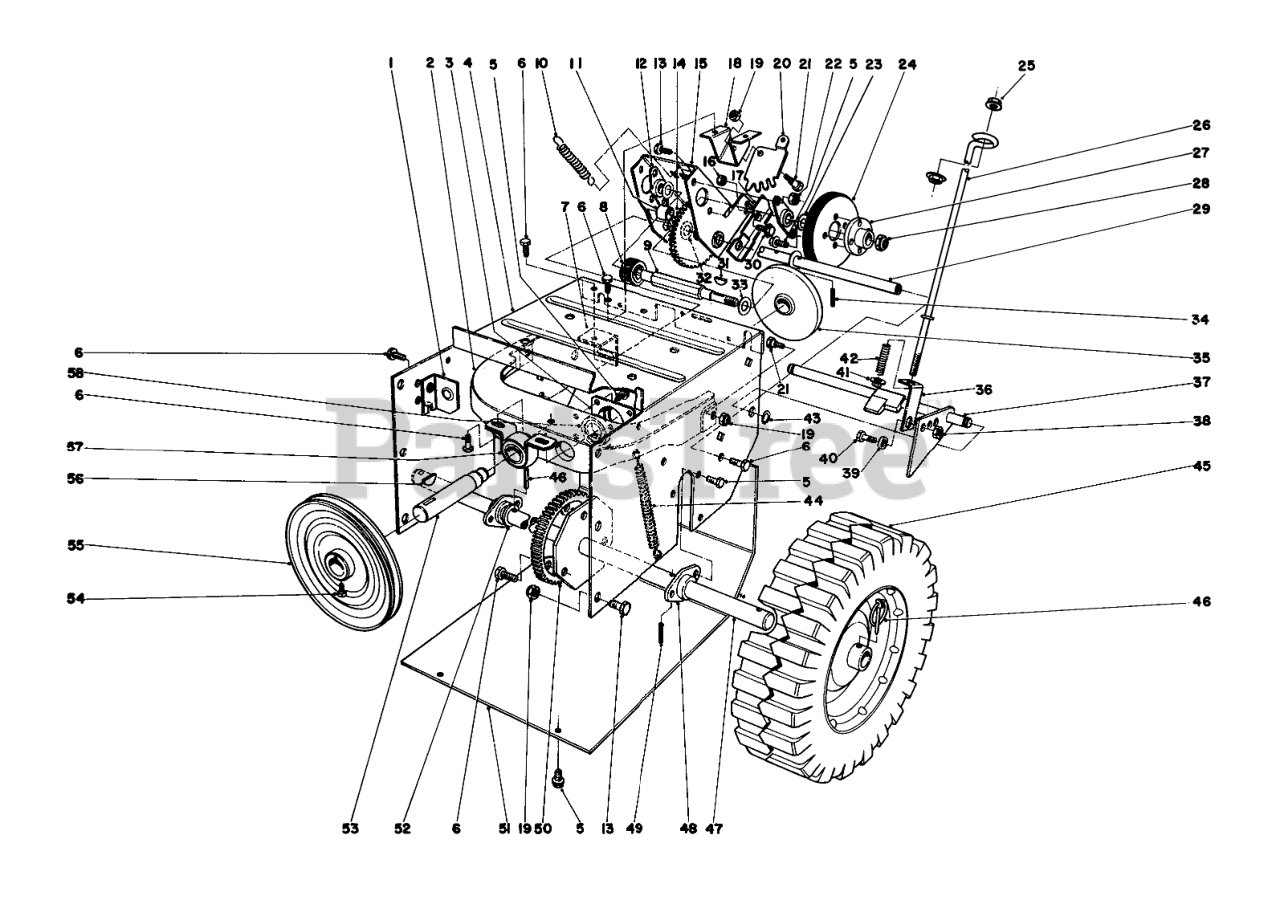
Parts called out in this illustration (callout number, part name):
1	AUGER CLUTCH MTG FRT
2	"OBS" FRICTION PLT FRAME
3	CUP-BEARING
4	Frame-Traction
5	SCREW
6	SCREW-HWHTF
7	BRACKET-MOUNT, REAR
8	PINION
9	SHAFT-WHEEL, FRICTION
10	SPRING-TRACTION
11	5/8ID X 1LG BUSHING
12	BEARING-WHEEL, FRICTION
13	SCREW-HH
14	Intermediate Gear (Incl. Ref. #11)
15	BRACKET-SLIDING
16	NUT-LOCK, NI
17	CAM-RECEIVER
18	MOUNT-LEVER
19	NUT-LOCK, NI
20	GEAR-QUADRANT
21	BOLT-SHOULDER
22	NUT-LOCK, CONE
23	WASHER-THRUST
24	WHEEL-FRICTION
25	NUT-HF
26	ROD-TRACTION, LOWER
27	HUB-WHEEL, FRICTION
28	NUT-LOCK, NI
29	SHAFT-PIVOT
30	Screw
31	KEY-WOODRUFF
32	WASHER-SPECIAL
33	WASHER-FLAT
34	PIN-SPRING
35	PLATE-FRICTION
36	BRACKET-TRACTION
37	Traction Engagement Arm
38	NUT-LOCK, CONE
39	Spacer-Traction Bracket
40	SCREW-HH
41	NUT-LOCK, HHF
42	SPRING
43	RING-RETAINING
44	SPRING-PLATE, FRICTION
45	Wheel
46	PIN-LYNCH
47	AXLE SHAFT WA
48	BEARING-AXLE
49	PIN-SPRING
50	GEAR-AXLE
51	Bottom Cover
52	WASHER-THRUST
53	Shaft Friction Plate
54	SCREW-SET, SQH
55	Pulley
56	KEY-WOODRUFF
57	BUSHING ASM
58	BEARING-BALL
